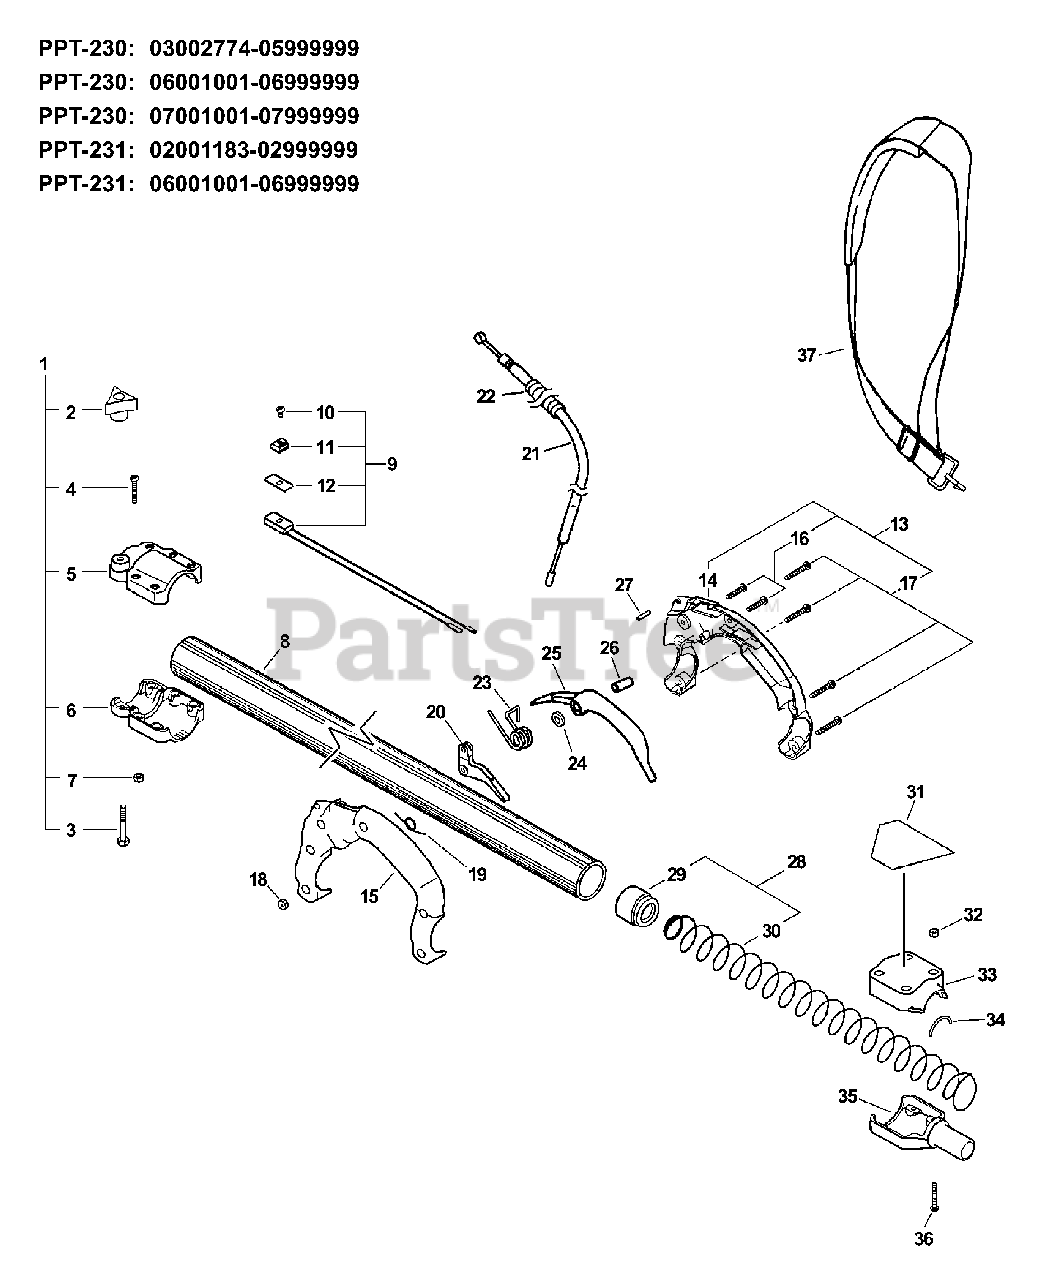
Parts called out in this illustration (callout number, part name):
1	COLLAR ASSY
2	THUMBSCREW
4	SCREW - 10-24 X 1-1/4"
5	COLLAR, MAIN PIPE - UPPER
6	COLLAR, MAIN PIPE - LOWER
7	LOCKNUT - 10-24
8	PIPE, MAIN - ORANGE
9	IGNITION SWITCH ASSY
10	SCREW - 3X10
11	KNOB, SWITCH - ORANGE
12	COVER, SWITCH - STOP
13	HANDLE ASSY - REAR
14	HANDLE, REAR - LEFT
15	HANDLE, REAR - RIGHT
16	SCREW - 10-24 X 1-1/4"
18	LOCKNUT - 10-24
19	SPRING, TRIGGER
20	TRIGGER, THROTTLE
21	CABLE, THROTTLE
22	TUBE, PROTECTIVE - CORRUGATED
23	SPRING, LOCKOUT LEVER
24	WASHER - 5
25	LOCKOUT, THROTTLE
26	COLLAR - 5
27	PIN - LOCATING
28	FLOATING BUSHING ASSY
29	BUSHING, FLOATING
31	LABEL - CAUTION
32	LOCKNUT - 10-24
33	CAP, LOWER SHAFT TUBE ADAPTER
35	ADAPTER, LOWER SHAFT TUBE
37	SHOULDER STRAP ASSY
